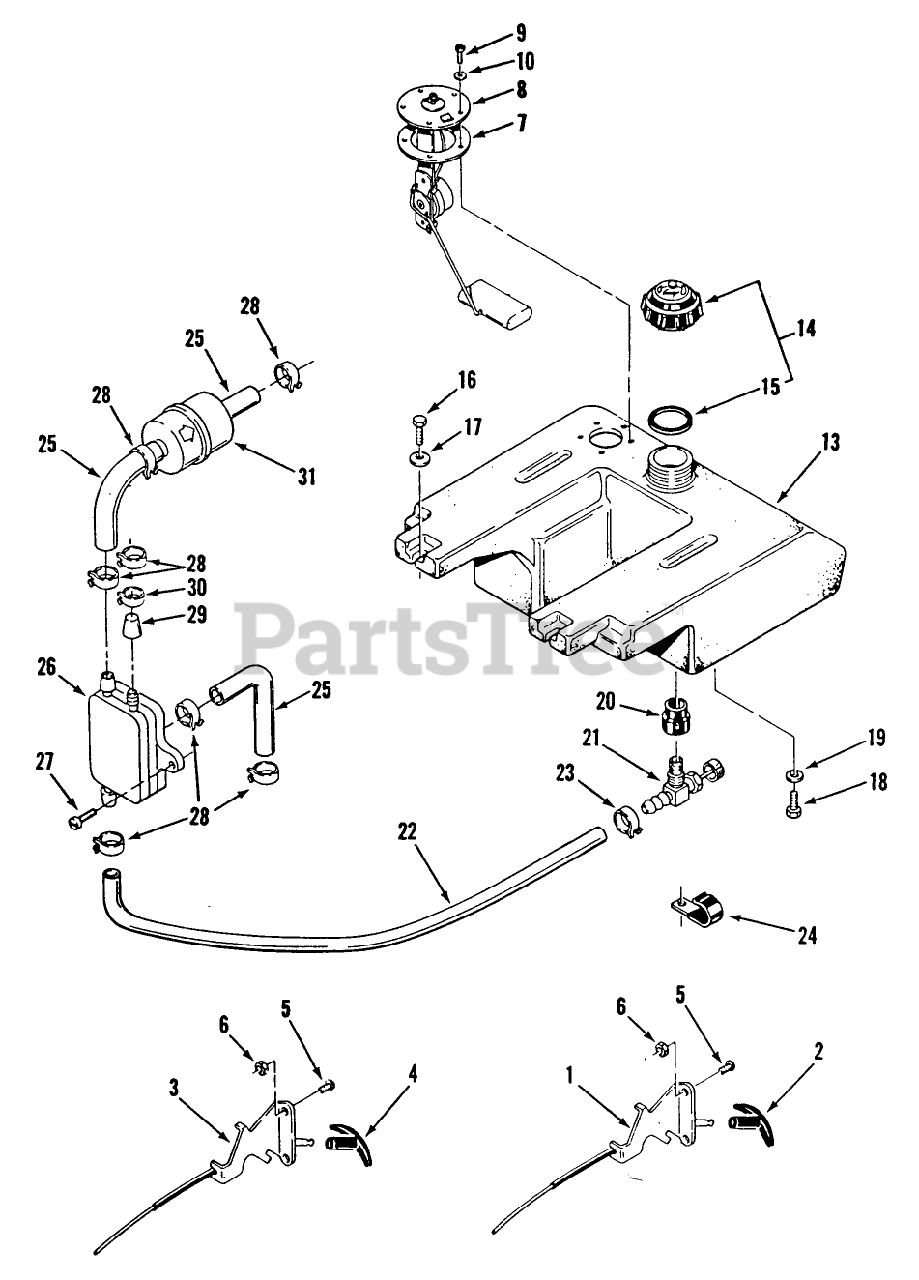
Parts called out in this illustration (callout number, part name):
1	CONTROL-THROTTLE
2	KNOB-THROTTLE
3	CONTROL-CHOKE
4	KNOB-CHOKE
5	SCREW-PPH
7	GASKET-SENDER, FUEL
14	ASS'Y-GAS CAP
21	VALVE-FUEL
